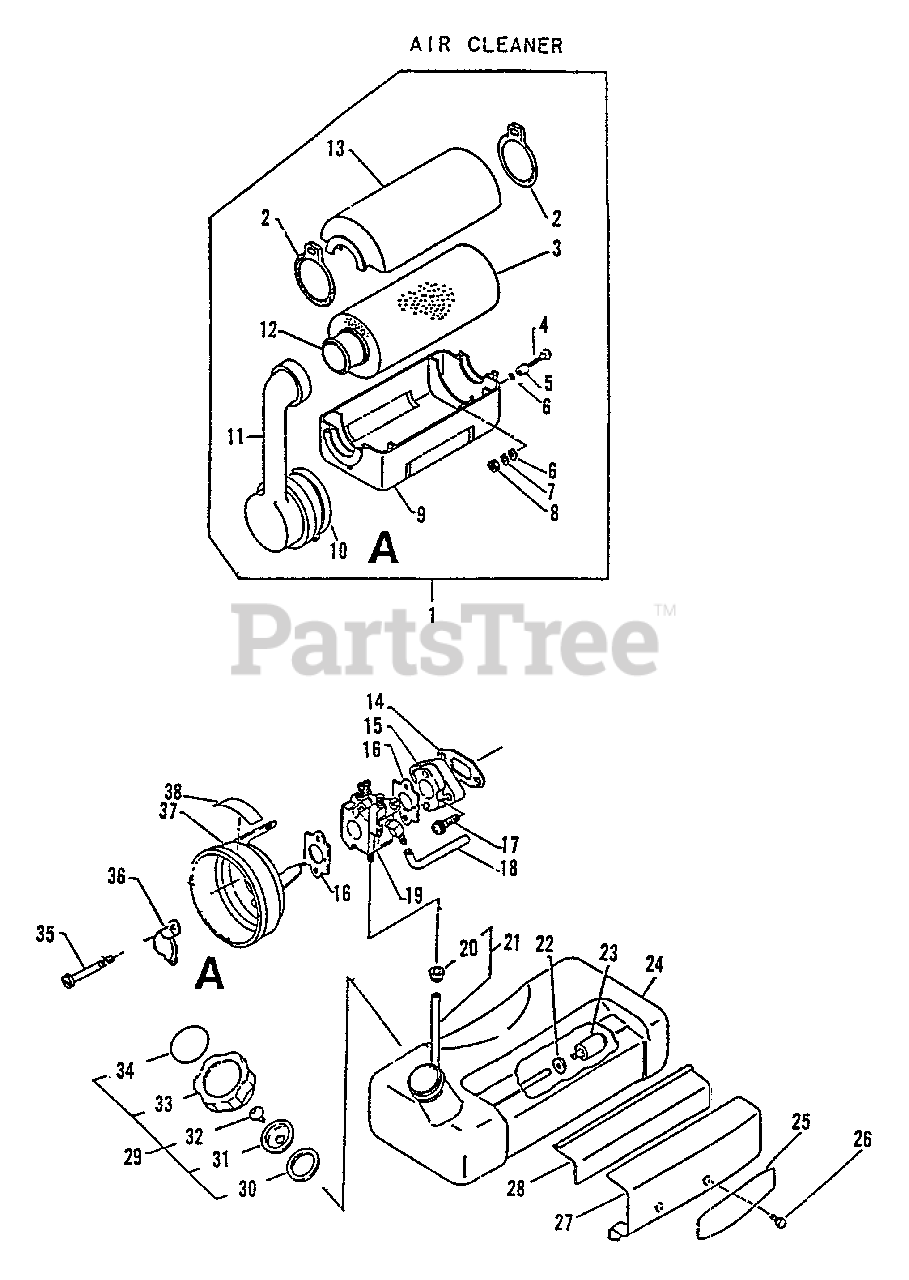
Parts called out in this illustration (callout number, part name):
1	AIR FILTER ASSY
3	FILTER, AIR
4	BOLT
6	WASHER, FLAT 5.5×10×0.8
7	WASHER, SPRING 5
8	NUT M5
9	CASE, AIR FILTER
10	CLAMP
11	ADAPTER, INTAKE
12	HOLDER, AIR FILTER
13	COVER, AIR FILTER
14	GASKET, INTAKE
15	INSULATOR
16	GASKET, INTAKE
17	SCREW 6×25
18	PIPE
19	CARBURETOR - WA-55
21	PIPE, FUEL W/GROMMET 3×5×250L
22	WASHER 5.5×12×0.8
23	FILTER, FUEL
24	TANK, FUEL
25	LABEL, LBB-4000
26	SCREW 5×10
27	BRACKET, FUEL TANK
28	CUSHION, FUEL TANK
29	CAP ASSY
30	GASKET
31	HOLDER, VENT
32	VALVE, CHECK
34	LABEL - FUEL MIX
35	BOLT
36	PLATE, PREVENT
37	CASE, AIR FILTER
38	LABEL - CHOKE
